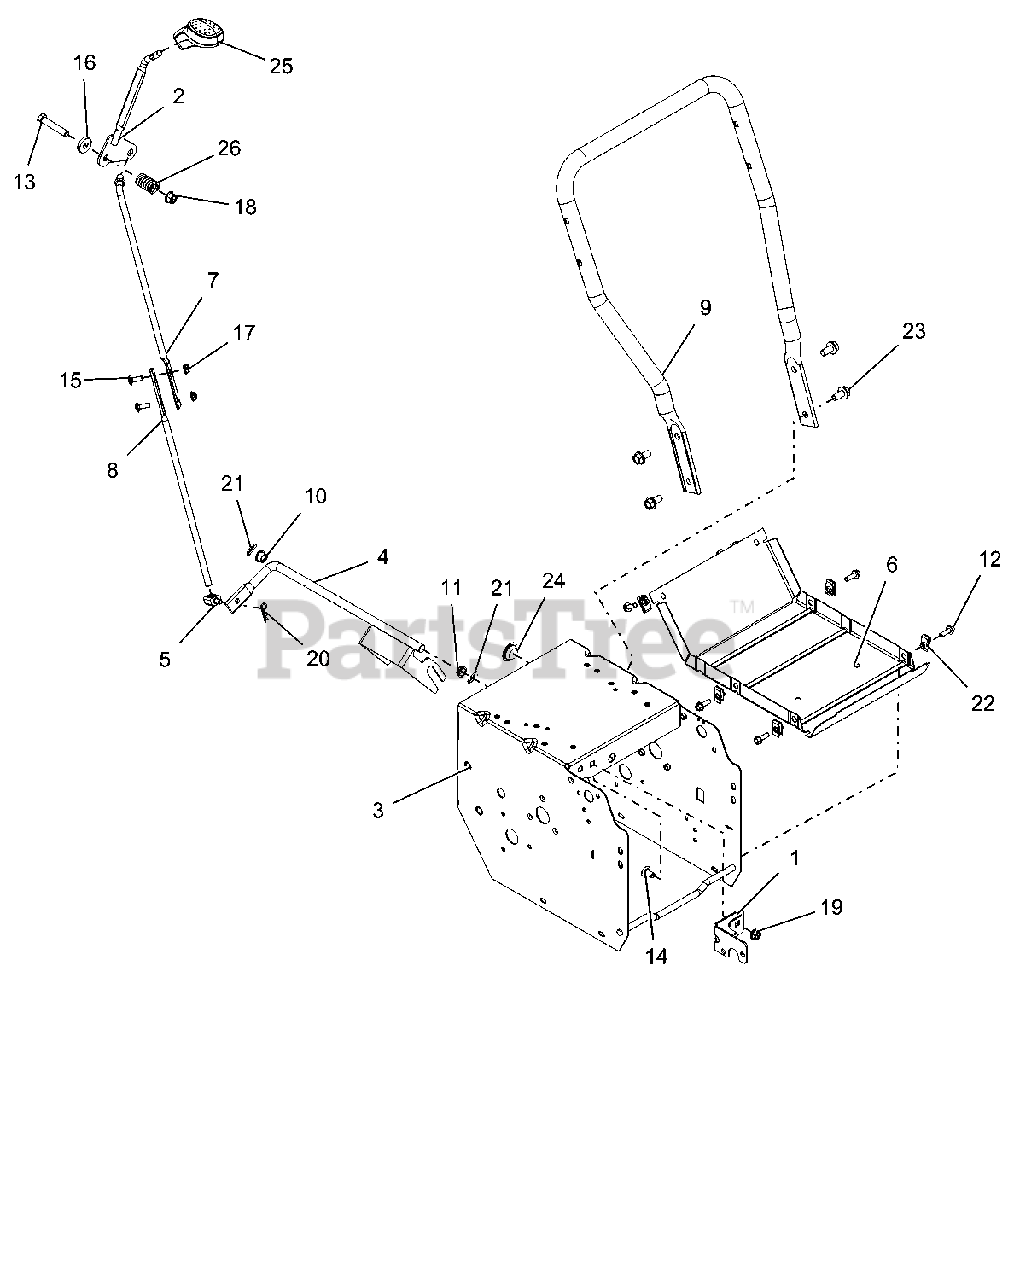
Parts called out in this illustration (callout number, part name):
1	WELDMENT, FRAME BRACKET
2	LEVER, CONTROL-SHIFT(WELDMENT)
3	WELDMENT, FRAME - DELUXE 16"
4	WELDMENT, SHIFT FORK
5	PIVOT,SHIFT ROD .375-16(TRUNN)
6	COVER, BOTTOM
7	ROD, SHIFT - UPPER
8	ROD, SHIFT - LOWER
9	HANDLEBAR, LOWER - SM DELUXE
10	BUSHING, POLYLINER-.50 SPLIT
11	BUSHING, POLYLINER-.50 SNAPIN
12	BLT-HEX .25-20X.75 HWH YZ GR5
13	@BLT-HEX .38-16X2.00 GR5 YWZC
14	@BLT-RHDSSQNK .31-18X.62 G5YZ
15	@BLT-RDHDSQNK .25-20X.75 G5YZ
16	WSHR-FL-STL .406X1.00X.188 YWZ
17	@NUT-LK-CTR-FLG .25-20 YWZC
18	@NUT-LK-TOP-FLG .38-16 YWZC
19	@NUT-LK-TOP-FLG .31-18 YWZC
20	PIN-HAIR INT .08X.18X1.18 YWZC
21	CLIP, SPRING
22	NUT-RTNR .25-20X.56
23	BLT-SERHFWH .38-16X.75 YWZC
24	PLUG, HOLE - .875" NYLON
25	KNOB, CONTROL, DASH
26	SG-COMP .125X.781X1.250
